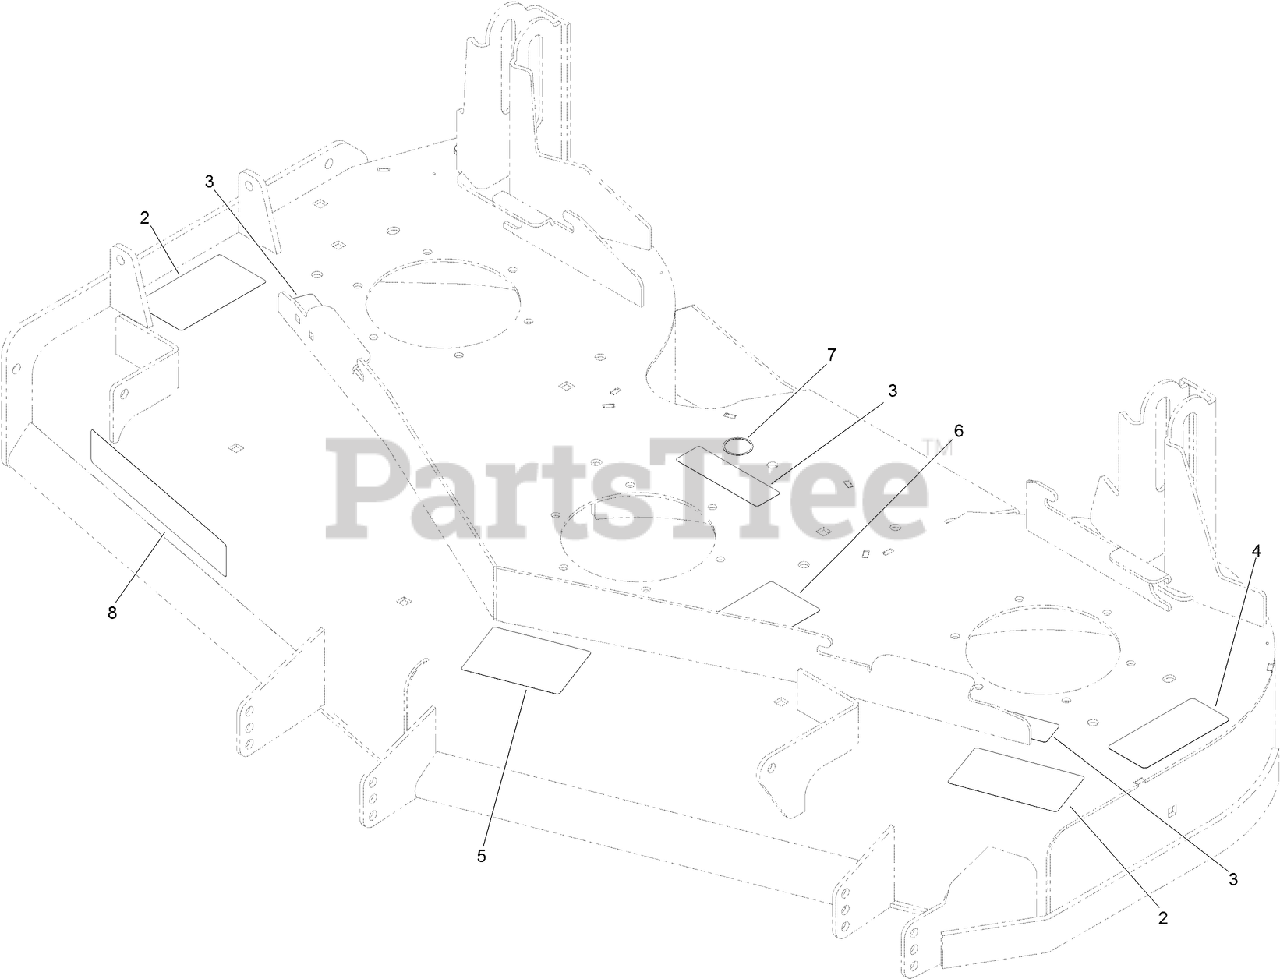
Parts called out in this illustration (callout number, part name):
2	DECAL-DANGER
3	DECAL-MISSING, COVER
4	DECAL-TORQUE, BLADE BOLT
5	DECAL-SCALP, ANTI
6	DECAL-ROUTING, DECK BELT
7	DECAL-GREASE
